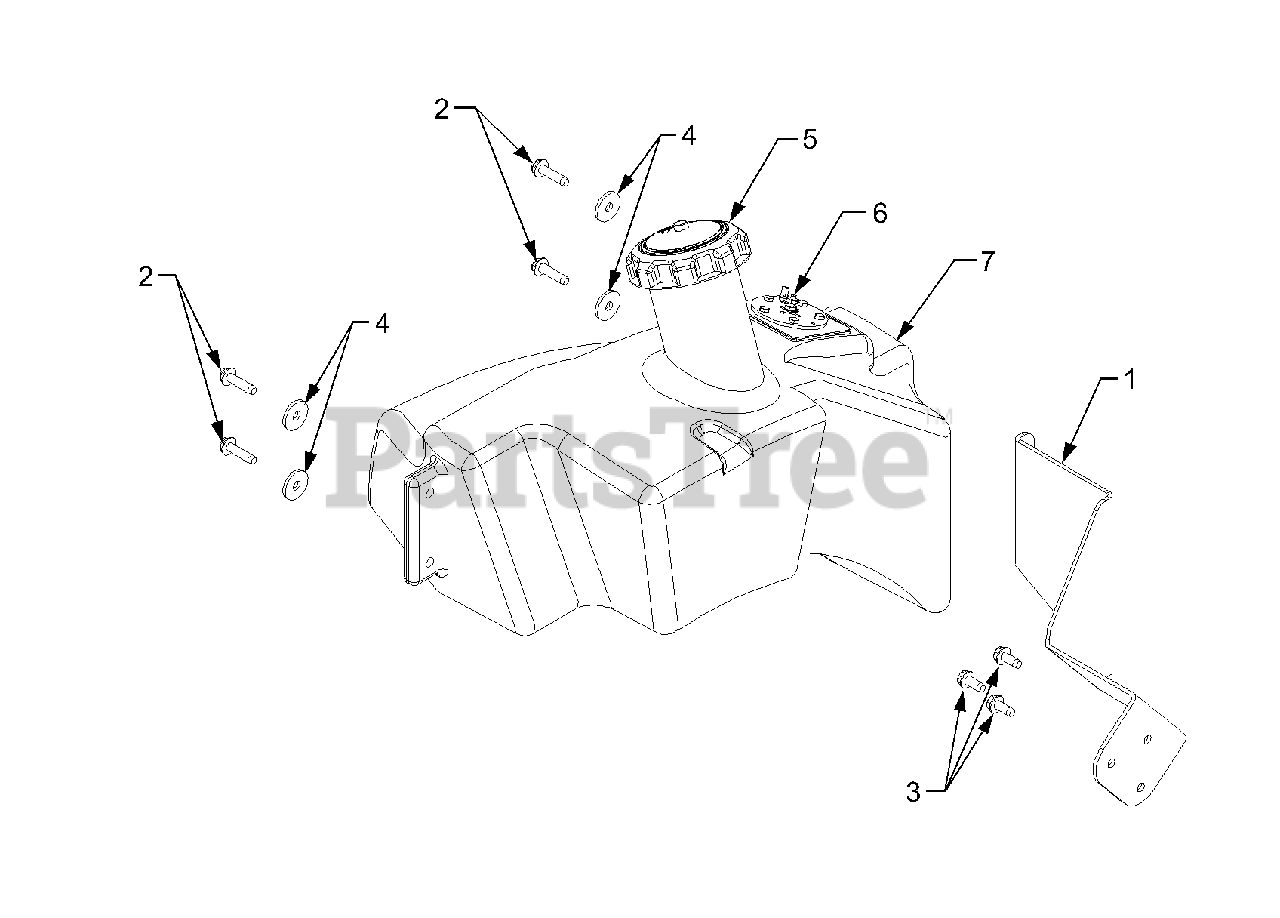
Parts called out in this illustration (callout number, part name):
1	Bracket, Front Tank Mtg.
2	Screw, Hex Wash Hd Tapp 5/16-18 x 1.25
3	Screw, Hex Wash Hd Tapp 5/16-18 x .75
4	Washer, Flat, .344 x 1.125 x .12
5	Cap, Fuel
6	Sensor, Fuel Level
7	Tank, Fuel
